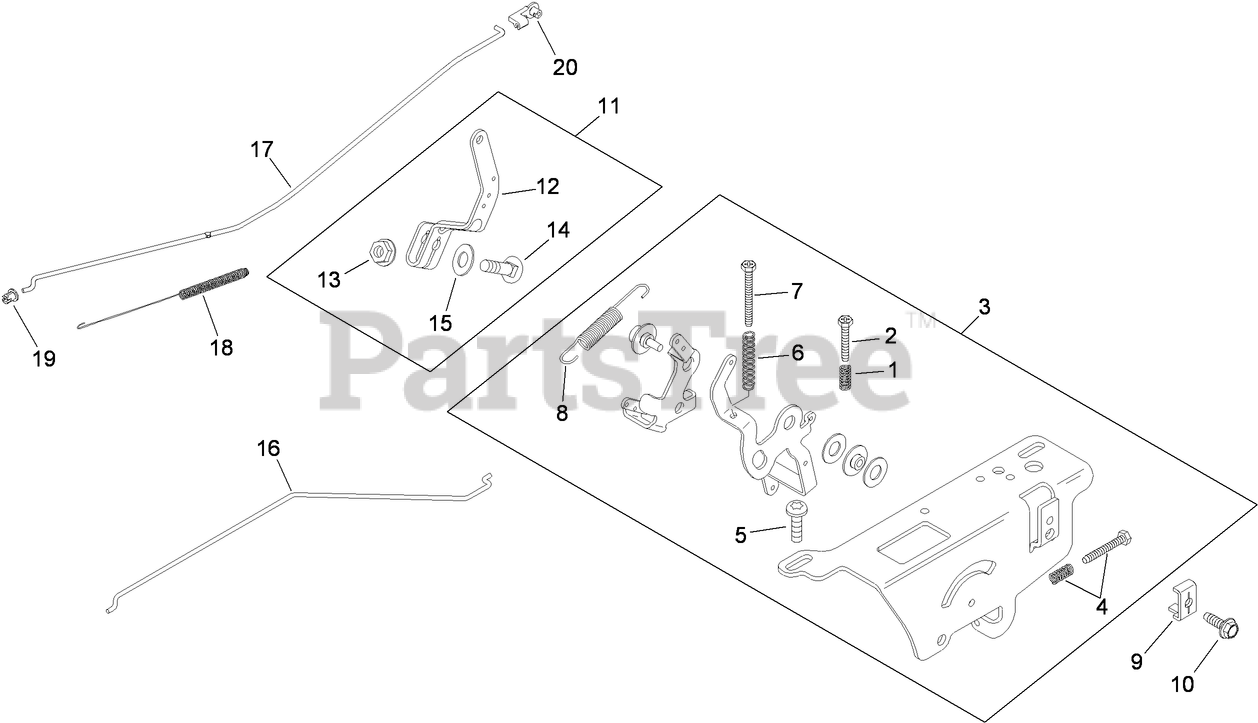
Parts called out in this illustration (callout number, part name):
1	Spring-Control, Speed
2	Screw-Thread Forming (M4x0.7x25)
3	Speed Control ASM
4	IDLE ADJUSTING SCREW AND SPRING KIT
5	Screw-Socket, 6 Lobed (Thread Forming, M6x1.0x20)
6	SPRING-CONTROL, SPEED (LONG)
7	SCREW-PHL THD FRM (M4X0.7X38)
8	Spring-Governor
9	CLAMP-CABLE
10	SCREW-FLANGE, THREAD FORMING (M5X0.8X16)
11	GOVERNOR LEVER ASM (INCLUDES REF 12-15)
12	Lever-Governor
13	Nut-Flange, Hex (1/4-20)
14	Bolt-Square Neck, Round Head (1/4-20x1)
15	Washer-Lock, Internal Tooth (1/4)
16	Linkage-Choke (Single Wire)
17	LINKAGE-THROTTLE
18	Spring-Linkage
19	BUSHING-LINKAGE, THROTTLE
20	BUSHING-RETAINING, LINKAGE
